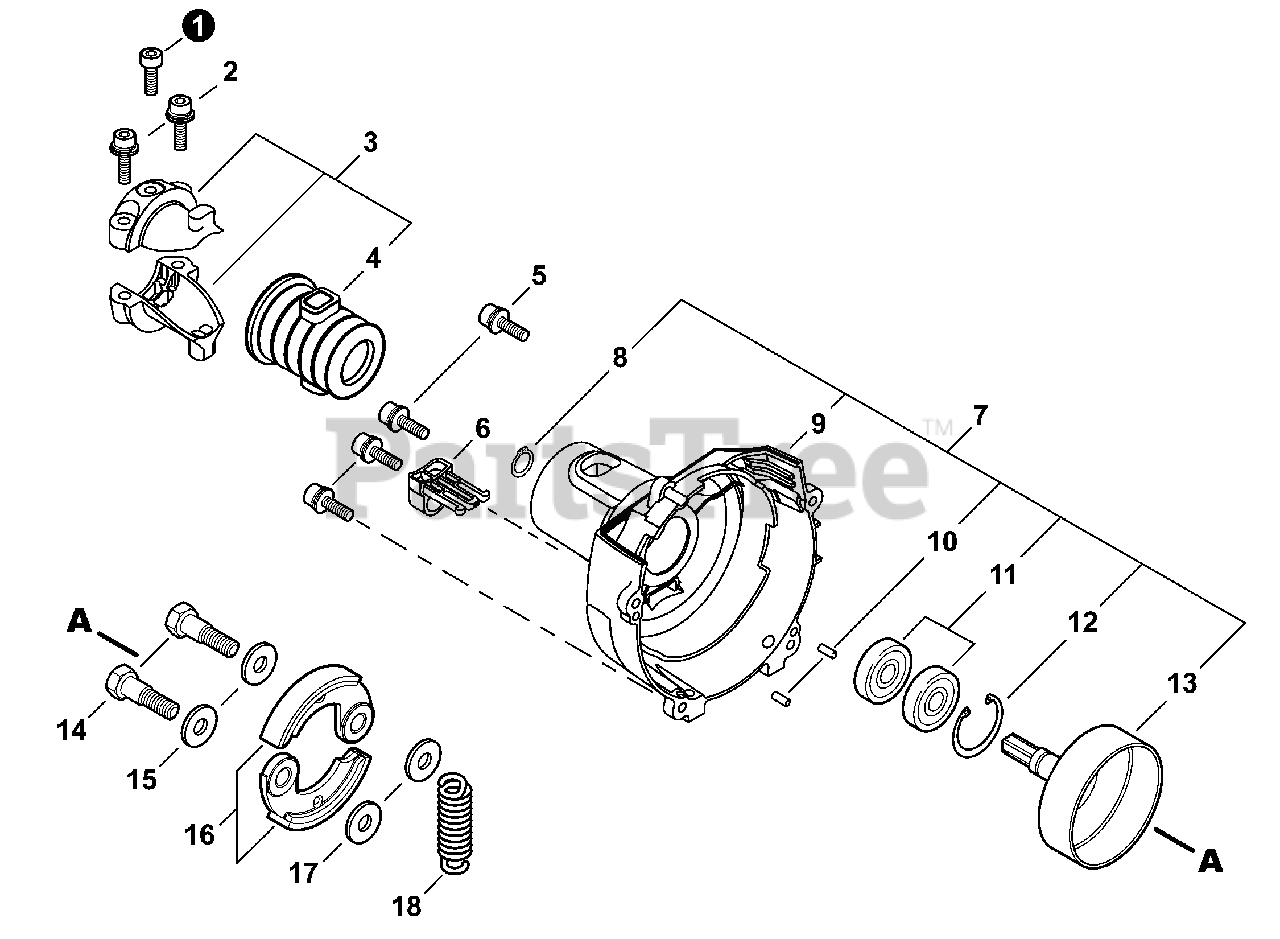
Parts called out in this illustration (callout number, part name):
1	BOLT 5×12
2	BOLT 5×25
3	HOLDER KIT, MAIN PIPE
4	CUSHION
5	BOLT 4×16
7	COVER ASSY, FAN
8	RING, RETAINING - 12
9	COVER, FAN
10	PIN, LOCATING 4
11	BEARING, BALL 6001
12	RING, SNAP 28
13	DRUM, CLUTCH
14	BOLT, CLUTCH 8×7.9×M6
15	WASHER, SPRING 8.5×16×0.5
16	SHOE, CLUTCH
17	WASHER 6.2×19×1.0
18	SPRING, CLUTCH
